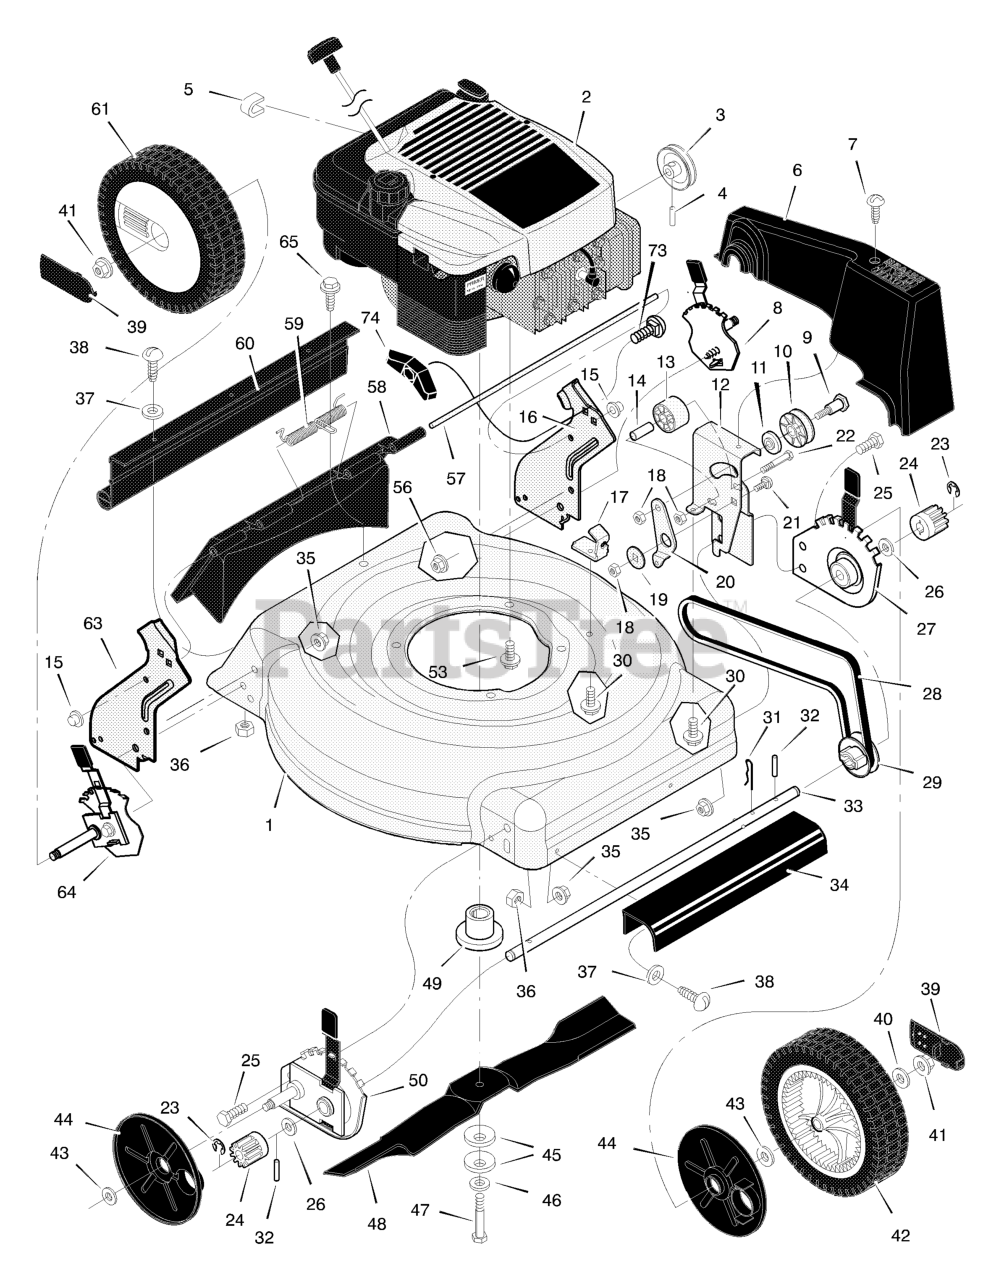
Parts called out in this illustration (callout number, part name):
1	Housing
2	Engine *
3	Pulley, Engine
4	Pin, Spring
6	Cover, Belt (Black)
8	Adjuster, Left Rear Height
9	Bolt, Shoulder
12	Bracket, Idler Support
13	Pulley, Idler
14	Bearing
15	Nut, Push
16	Bracket, Left Handle
17	Bracket, Cable
18	Nut, Hex
20	Arm, Idler
21	Bolt, Carriage
22	Bolt, Shoulder
23	E--Ring
24	Gear, Pinion
25	Bolt
27	Adjuster, Left Frt. Height
29	Pulley, Axle
31	Pin, Hair
32	Pin, Spring
34	Cover, Axle (Black)
35	Nut, Flange
36	Nut, Hex
39	Cap, Hub
40	Washer
41	Nut, Flange
42	Wheel, Drive
44	Cover, Dust
45	Washer, Belleville
49	Adapter, Blade
50	Adjuster, Right Frt. Height
53	Bolt, Engine
55	Washer
56	Nut, Flange
57	Rod, Pivot
58	Door, Rear (Black)
60	Deflector, Rear
61	Wheel, Rear
63	Bracket, Right Handle
64	Adjuster, Right Rear Hgt.
73	Bolt, Carriage
